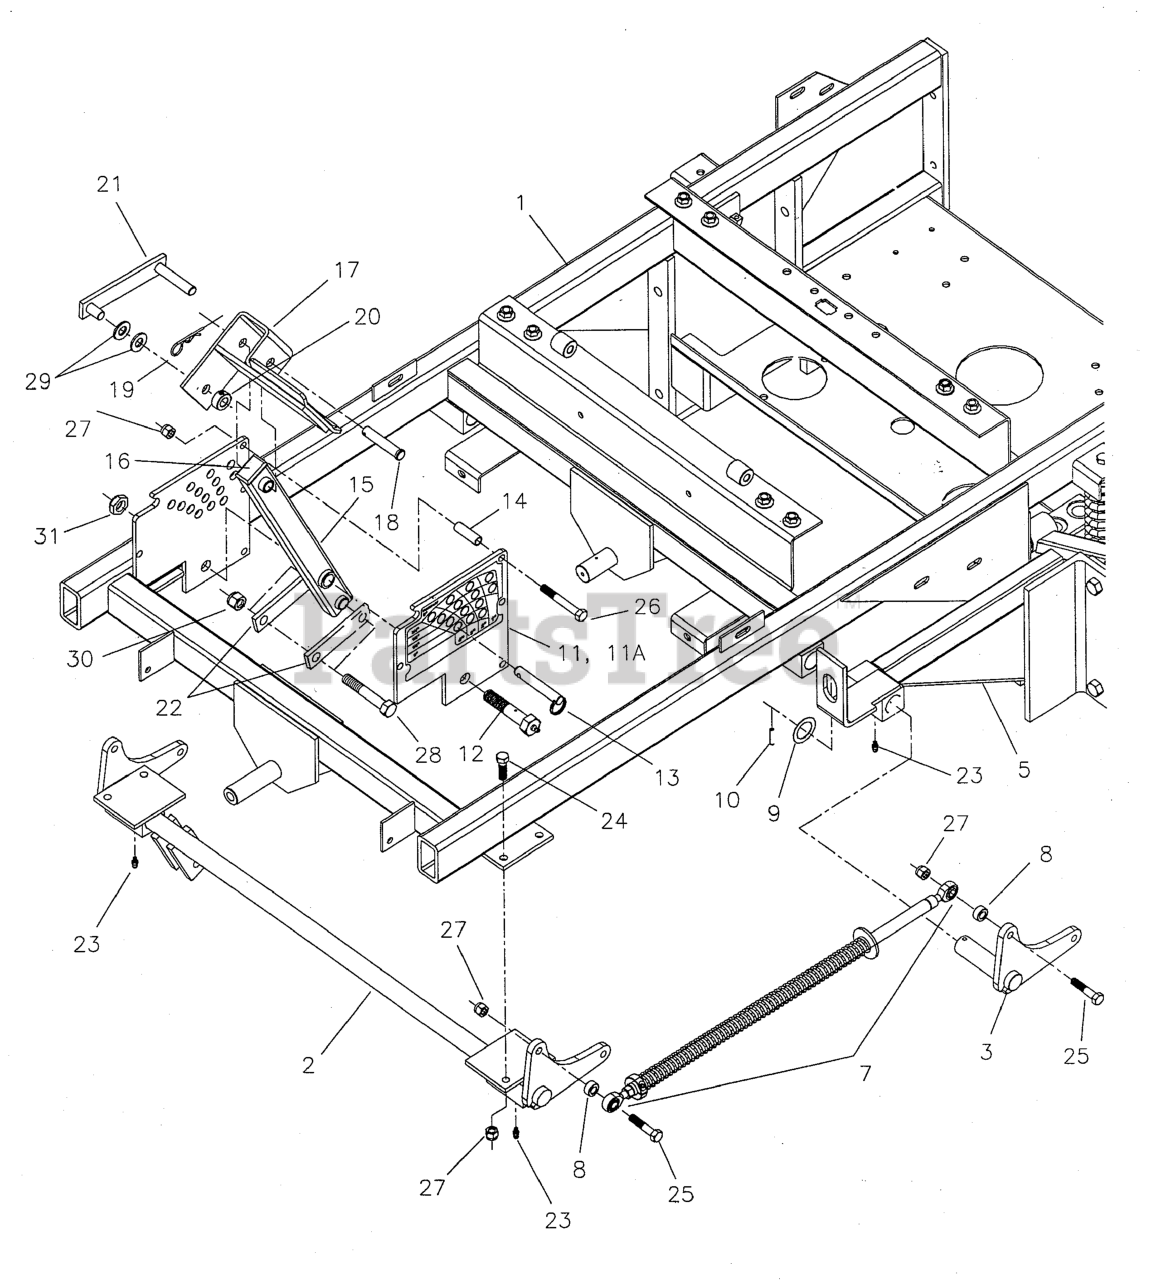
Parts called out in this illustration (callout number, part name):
1	FRAME, I.S. Main
2	SHAFT, Front Deck Lift
3	LIFT PIVOT, Left
5	REAR DECK LIFT FRAME - LH
7	DECK LIFT SPRING ROD ASSEMBLY
8	SPACER, .39 x .75 x .38
10	PIN, Roll, 3/16 x 1
11	LIFT PLATE ASSEMBLY
11	DECAL, Deck Height
11A	ISZ Lift Plate Assembly
11A	DECAL, Deck Height
12	LIFT PIVOT BOLT
13	PIN, 1/2 x 3
14	SPACER, .38 x .50 x 1.56
15	ARM, Deck Lift Pivot
16	CAP
17	FOOT PEDAL ASSEMBLY
17	PEDAL SAFETY WALK
18	PIN, Clevis, 1/2 x 2-1/2
19	HAIRPIN CLIP
20	COLLAR, 1/2" Set
21	DECK LIFT LOCK
22	DECK LIFT LINK
23	GREASE FITTING
24	BOLT, 3/8-16 X 1-1/4" GD5 CZ
25	BOLT, 3/8-16 X 1-3/4" GD5 CZ
26	BOLT, 3/8-16 X 2-3/4" GD5 CZ
27	NUT, 3/8-16 HEX NYLON LOCK
28	BOLT, 1/2-20 x 3
29	WASHER, 1/2 SAE
30	NUT, Hex, Nylon Lock, 1/2-20
31	NUT, 5/8-11 Hex Jam Nylon Lock
